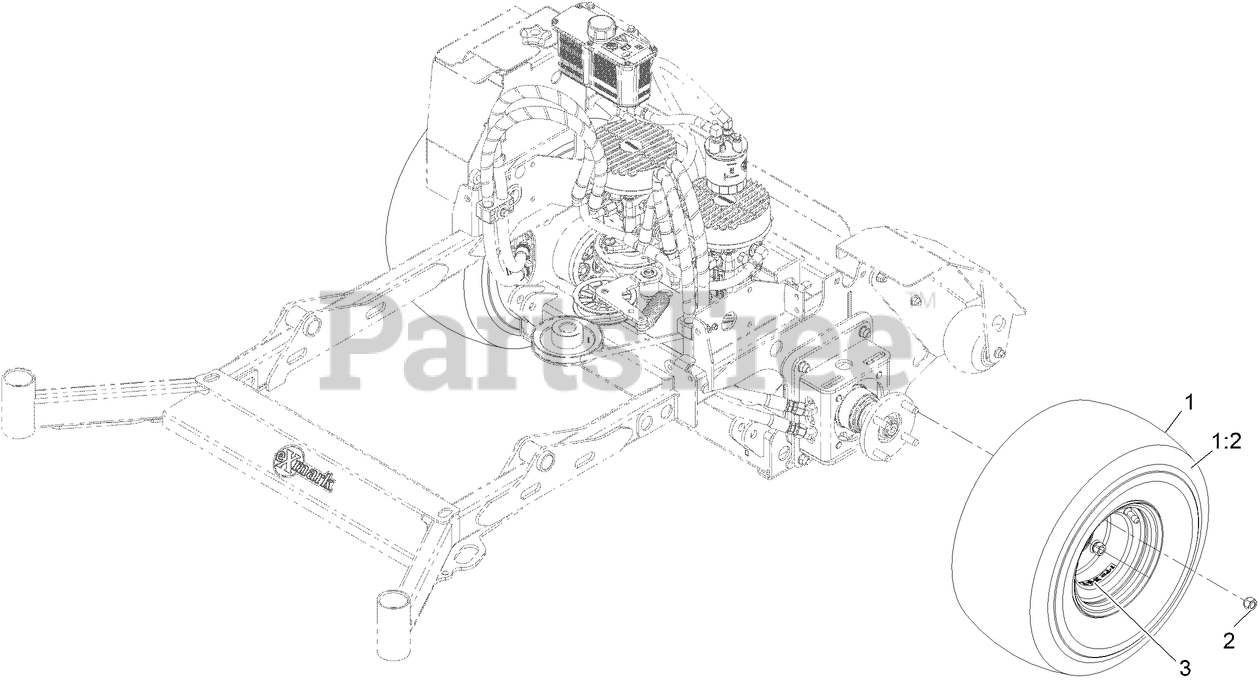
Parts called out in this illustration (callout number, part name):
1	Wheel/Tire ASM
2	NUT-LUG
3	DECAL-TORQUE, WHEEL HUB LUG
